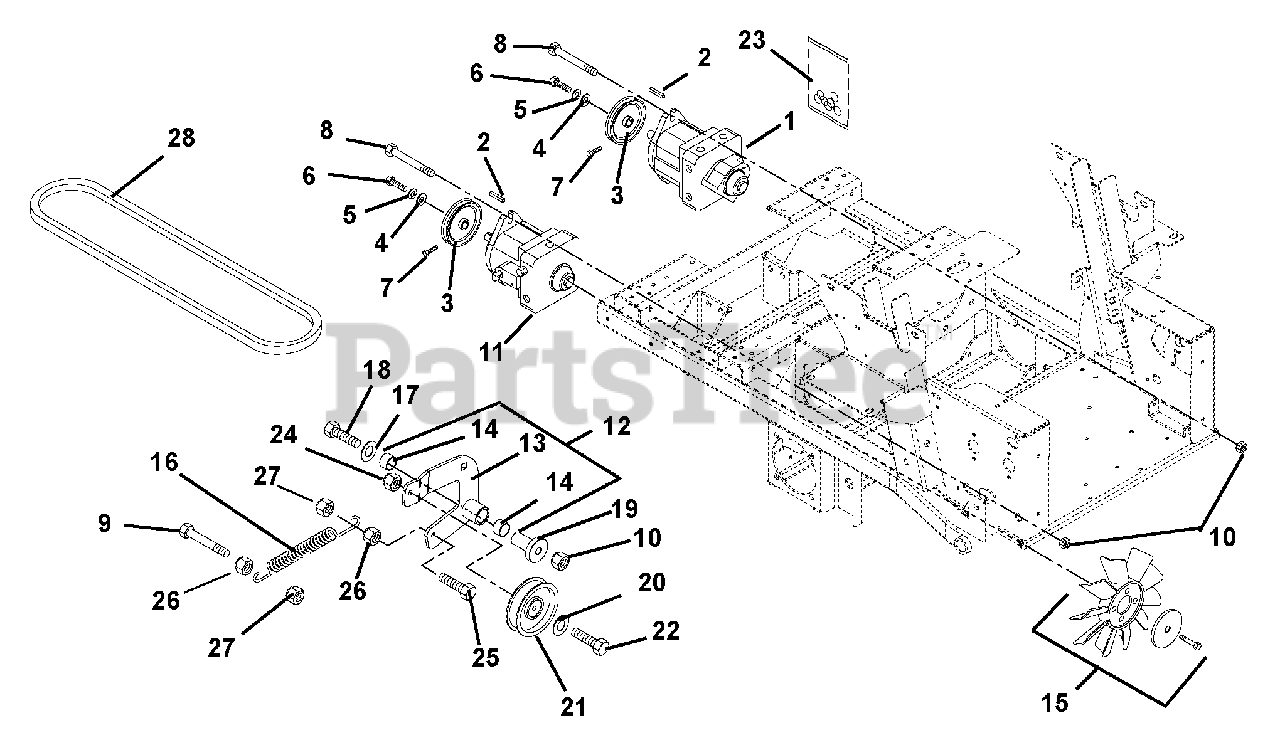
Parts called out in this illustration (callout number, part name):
1	Pump, Hydraulic (RTN) with Auxiliary
1	Pump, hydraulic (LH) without Auxiliary
2	Key, Square 5 x 5 x 30mm Plain
3	Sheave, Poly-V .671 x 4.125
4	Washer, Pump .28 x 1.25 x .50
5	Washer, Locking .25 x .062
6	Bolt, Hex M6 x 1 x 16
7	Screw, Socket Head .25-20 x .50
8	Bolt, Hex .50-13 x 1.50 Grade 5
9	Bolt, Hex .31-18 x 2.50 Grade 5
10	Nut, Locking Top Flange .50-13
11	Pump, Hydraulic (RTN)
12	Assembly, Idler Arm Guard Drive
13	Weldment, Idler Arm Ground Drive
14	Bearing, 1.00 x 1.12 x .75
15	Fan, Hydro Pump Cooling
16	Spring, Tension .120 x .845 x 6.500
17	Washer, Flat Steel .39 x.75 x.125
18	Bolt, Hex .50-13 x 3.50 Grade 5
19	Bearing, Pedestal Powdered Metal
20	Washer, Flat Steel .406 x .812 x .065
21	Idler, Flat 4.00 x .38
22	Bolt, Hex .38-16 x 2.25 Grade 5
23	Kit, Pump Seal
24	Nut, Locking Top Flange .38-16
25	Bolt, Hex .31-18 x 1.25 Grade 5
26	Nut, Hex .31-18
27	Nut, Locking Top Flange .31-18
28	Belt, Poly-V 49.50
